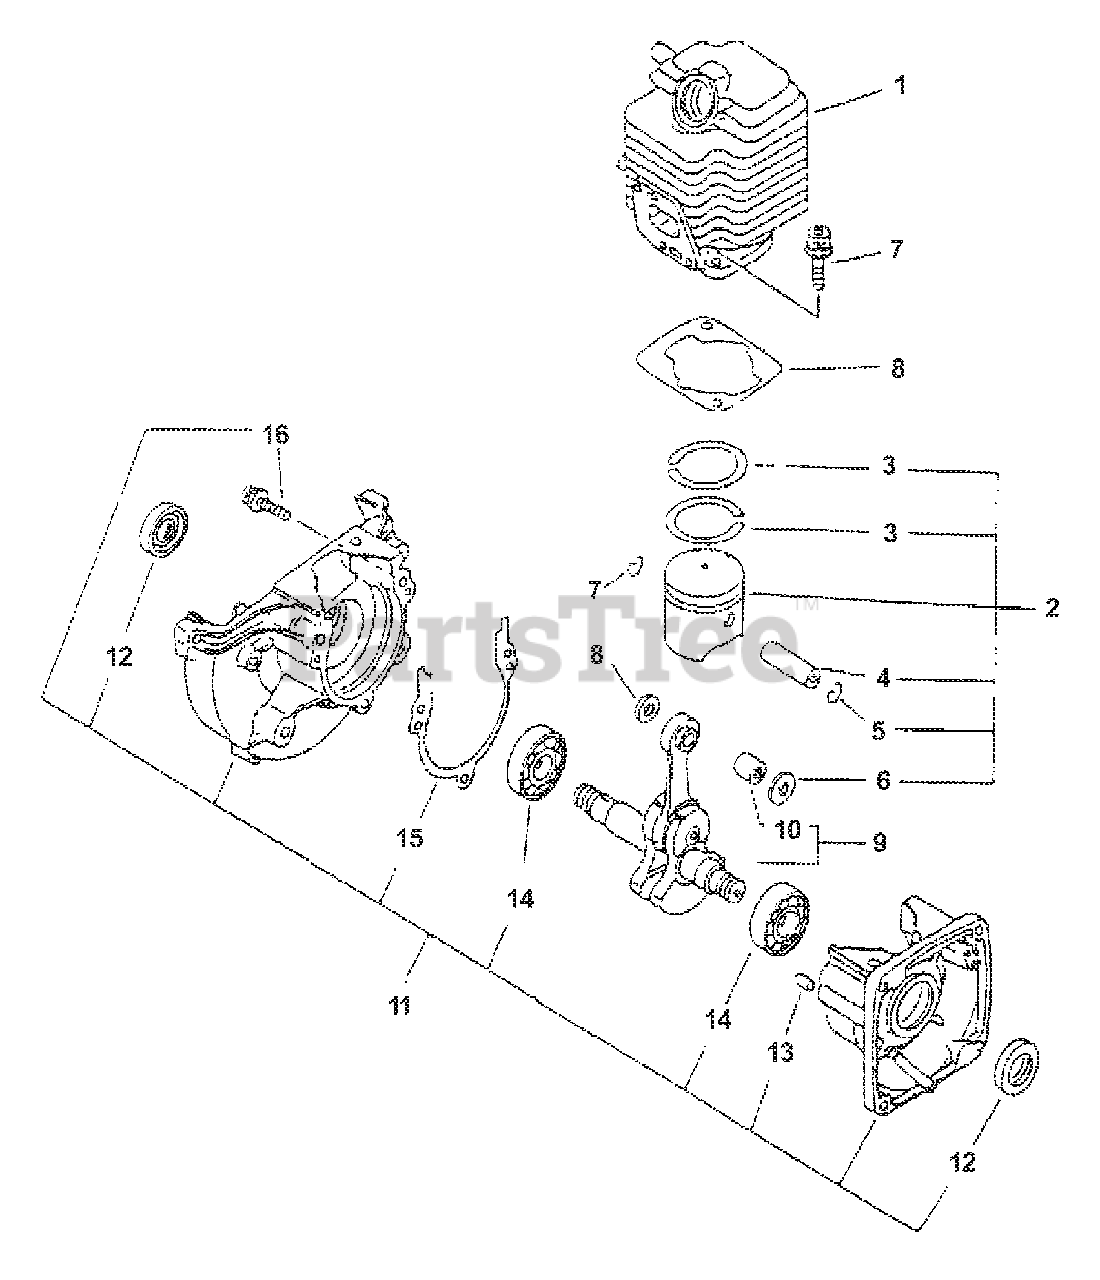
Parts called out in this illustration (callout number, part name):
1	CYLINDER
2	PISTON KIT
3	RING, PISTON
4	PIN, PISTON
5	RING, RETAINING
6	SPACER, PISTON
7	SCREW - 5X22
8	GASKET, CYLINDER
9	CRANKSHAFT ASSY
10	BEARING, NEEDLE
11	CRANKCASE KIT
12	SEAL, OIL
13	PIN - LOCATING
14	BEARING, BALL - 6201
15	GASKET, CRANKCASE
16	SCREW - 5X28
